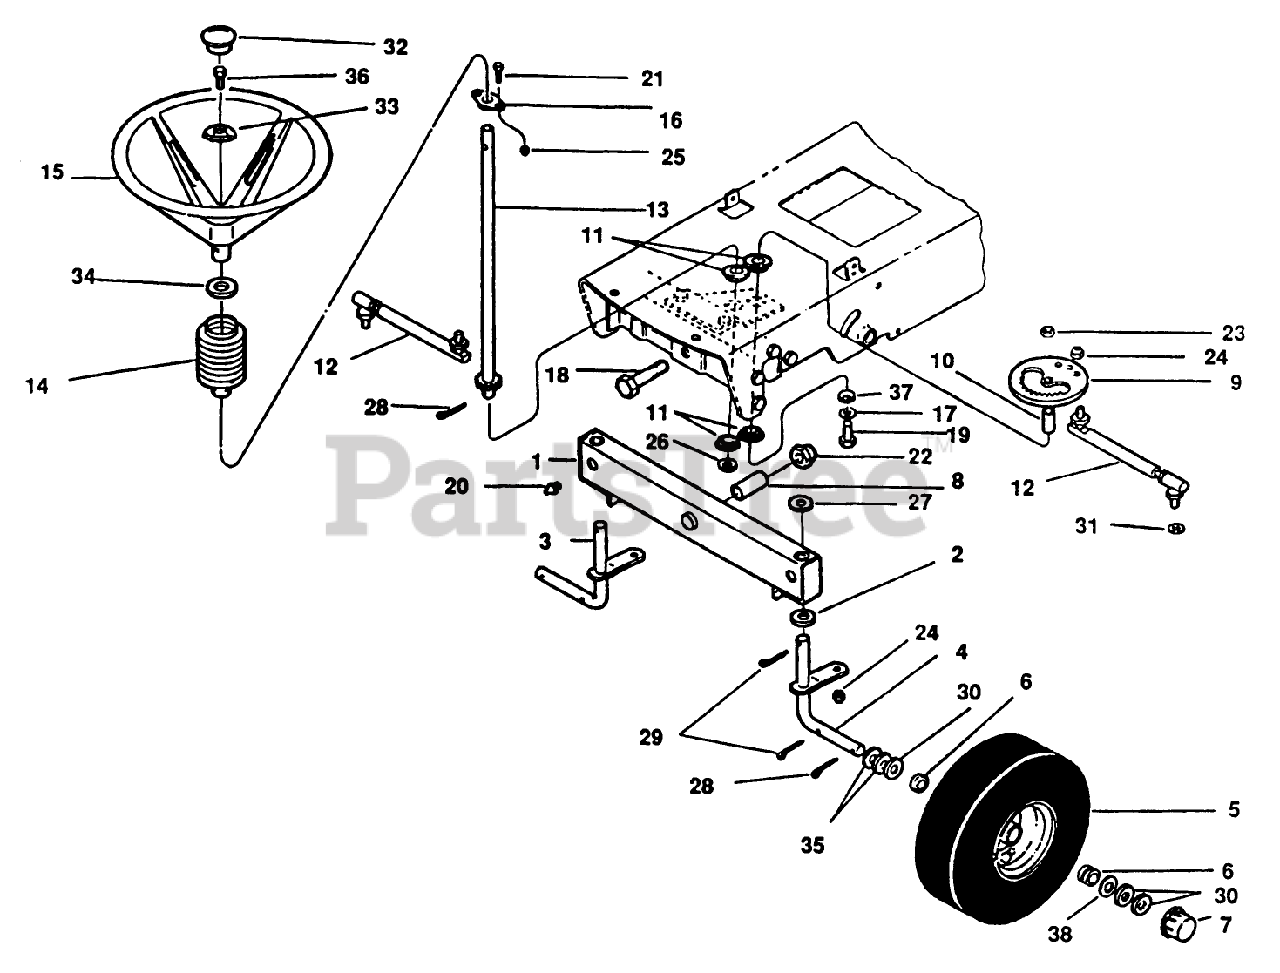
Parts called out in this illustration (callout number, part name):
3	RH FRT SPDL WA (BLUE)
8	SPACER
10	SPACER
11	BEARING - FLANGE
12	BALL JOINT
13	STEERING SHAFT WA
16	BEARING AY.
17	WASHER
21	SCREW-HH
22	NUT-HEX CONE LOK
23	NUT-HEX
24	HEX NUT
25	NUT-LOCK, CONE
26	SPACER
30	WASHER
36	SCREW - HEX
